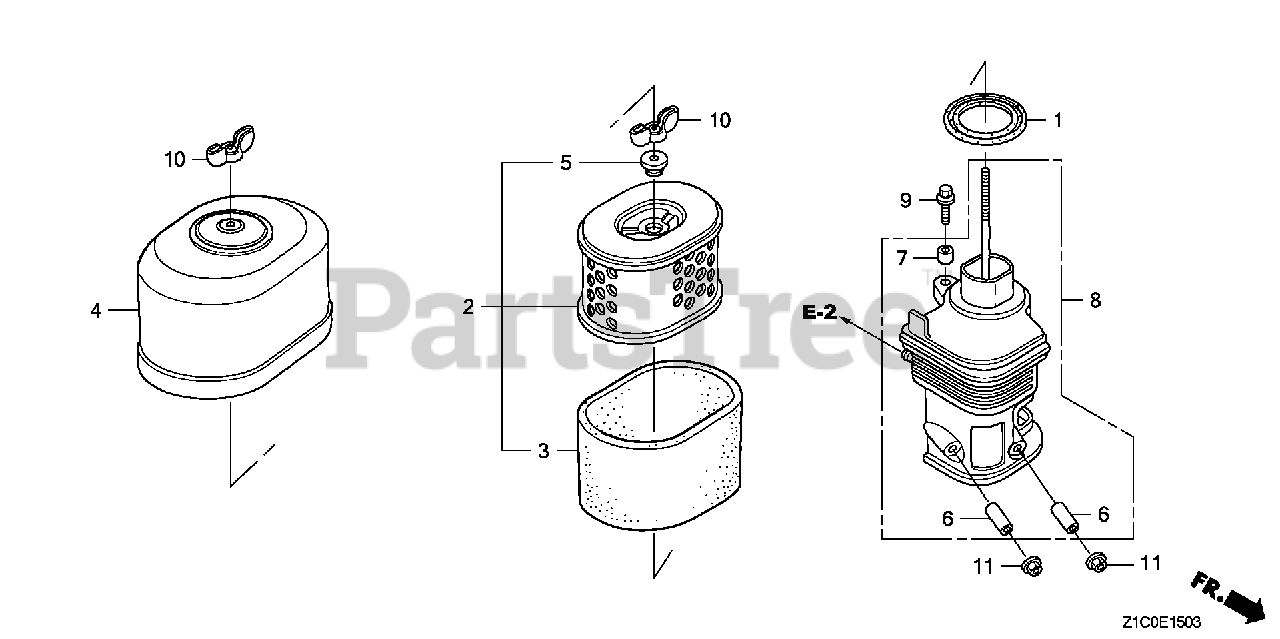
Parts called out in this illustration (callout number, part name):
1	GASKET, ELBOW
2	ELEMENT, AIR CLEANER
3	FILTER (OUTER)
4	COVER, AIR CLEANER (STD)
5	GROMMET, AIR CLEANER
6	COLLAR, AIR CLEANER
7	COLLAR B, AIR CLEANER
8	ELBOW, AIR CLEANER
9	BOLT-WASHER (6X22)
10	WINGNUT, TOOL BOX SETTING
11	NUT, FLANGE (6MM)
